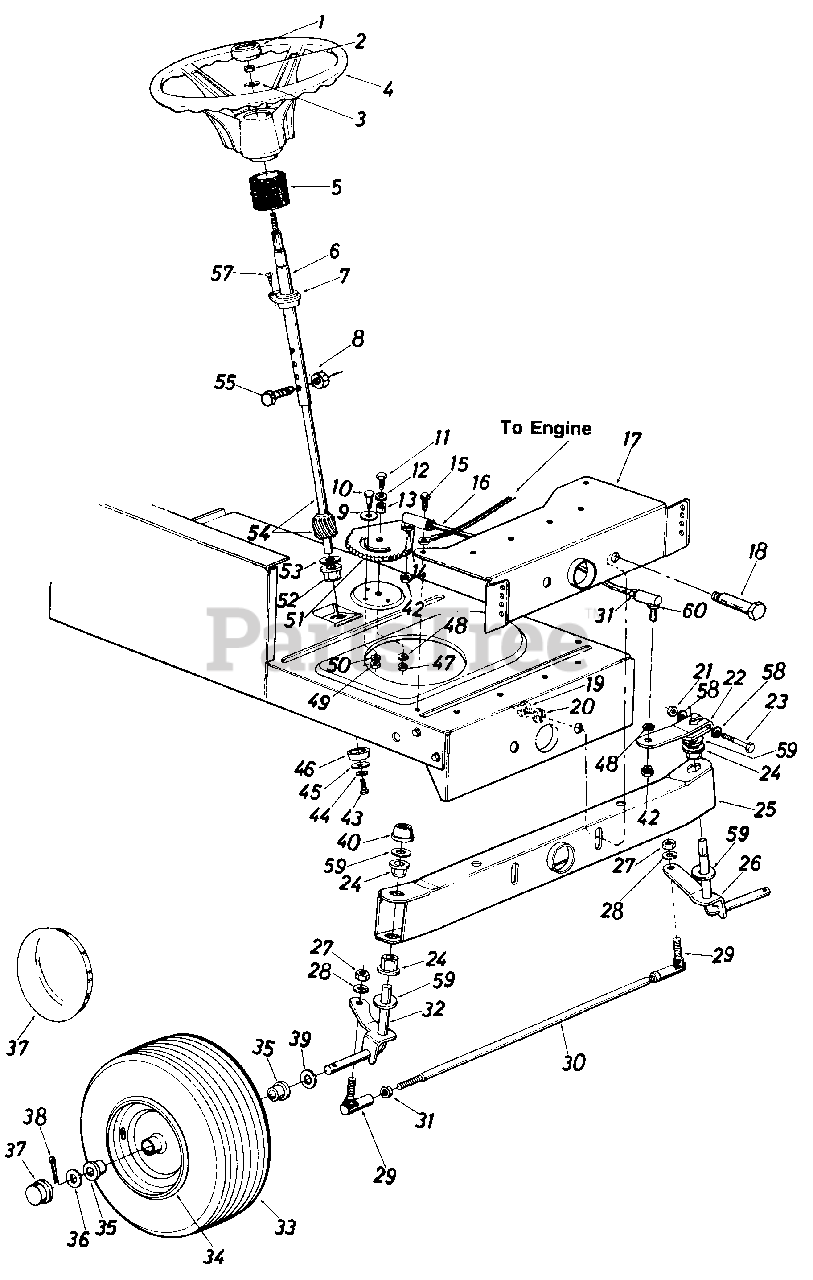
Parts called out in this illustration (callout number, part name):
1	Steering Wheel Cap
2	Hex L-Nut 5/16-18 Thd
3	Belleville Wash. .345" I.D.
4	Steering Wheel 12" Dia.
5	Steering Bellow
6	Steering Column Ass'y.
7	Flange Bearing .890 I.D. x 1.36 O.D.
8	Hex L-Nut 1/4-20 Thd.
9	Fl-Wash. .438" I.D. x 1.37
10	Shoulder Bolt .437" Dia. x .35 Lg. 5/16-18 Thd.
11	Hex Bolt 3/8-24 x 1.0" Lg. (Grade 5)
12	Fl-Wash. .38" I.D. x 1.0"
13	Spacer .380" I.D. x .625" O.D. x .227
14	L-Wash. 3/8" I.D.
15	Hex Wash. Hd. Self-Tap Scr.
16	Steering Drag Link
17	Front Pivot Brkt.
18	Shoulder Bolt .498" Dia. x 2.04 Lg. 3/8-16 Thd.
19	Hex Nut 3/8-16 Thd.
20	L-Wash. 3/8" I.D.
21	Hex Cent. L-Nut 5/16-24 Thd.
22	Steering Arm Front Axle
23	Hex Bolt 5/16-24 x 2.00" Lg. (Grade 5)
24	Hex Flg. Brg. .634 I.D.
26	Front Axle Ass'y.-L.H.
27	Hex Nut 3/8-24 Thd.
28	L-Wash. 3/8" I.D.
29	Ball Joint 3/8-24 Thd.
30	Tie Rod
31	Hex Jam Nut 3/8-24 Thd.*
32	Front Axle Ass'y.-R.H.
33	Wheel Ass'y. Comp.
34	Front Wheel Rim Only
35	Bearing
36	Fl-Wash. .640" I.D. x 1.54" O.D.
37	Front Wheel Hub Cap
38	Cotter Pin 1/8 Dia. x 1.25" Lg.
39	Fl-Wash. .640" I.D. x .24" O.D.
40	Push Cap 5/8" Dia. Rod
42	Hex Nut 3/8-24 Thd.
43	Hex L-Bolt 5/16-18 x .62"
44	L-Wash. 5/16" I.D.
45	Fl-Wash. .3441' I.D. x 1.25" O.D.
46	Spacer (Plastic)
47	Hex Nut 3/8-24 Thd.
48	L-Wash. 3/8" I.D.
49	Hex Nut 5/16-18 Thd.
50	L-Wash. 5/16" I.D.
51	Steering Gear Segment
52	Hex Flg. Brg. .634 I.D.
53	Fl-Wash. (Hardened)
54	Steering Shaft Lower
55	Hex Bolty 1/4-20 x 1.31" Lg.
57	Oval Hd. Cr.-Sunk Scr. #10 x 5/8" Lg.
58	Wave Wash. .32" I.D. x .62"
59	Fl-Wash. (Hardened)
60	Drag Link Ball Joint 3/8-24 Thd.
